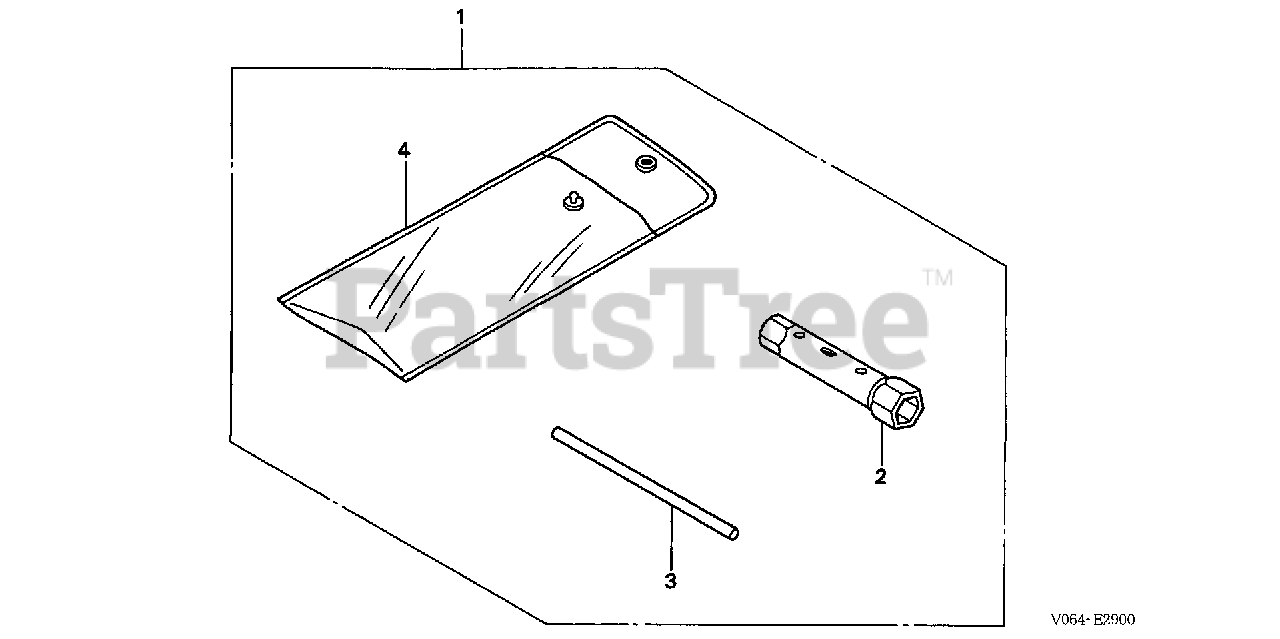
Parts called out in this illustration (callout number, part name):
1	TOOL KIT (NOT AVAILABLE)
2	WRENCH, SPARK PLUG
3	BAR A, HANDLE
4	BAG, TOOL (160MM)
